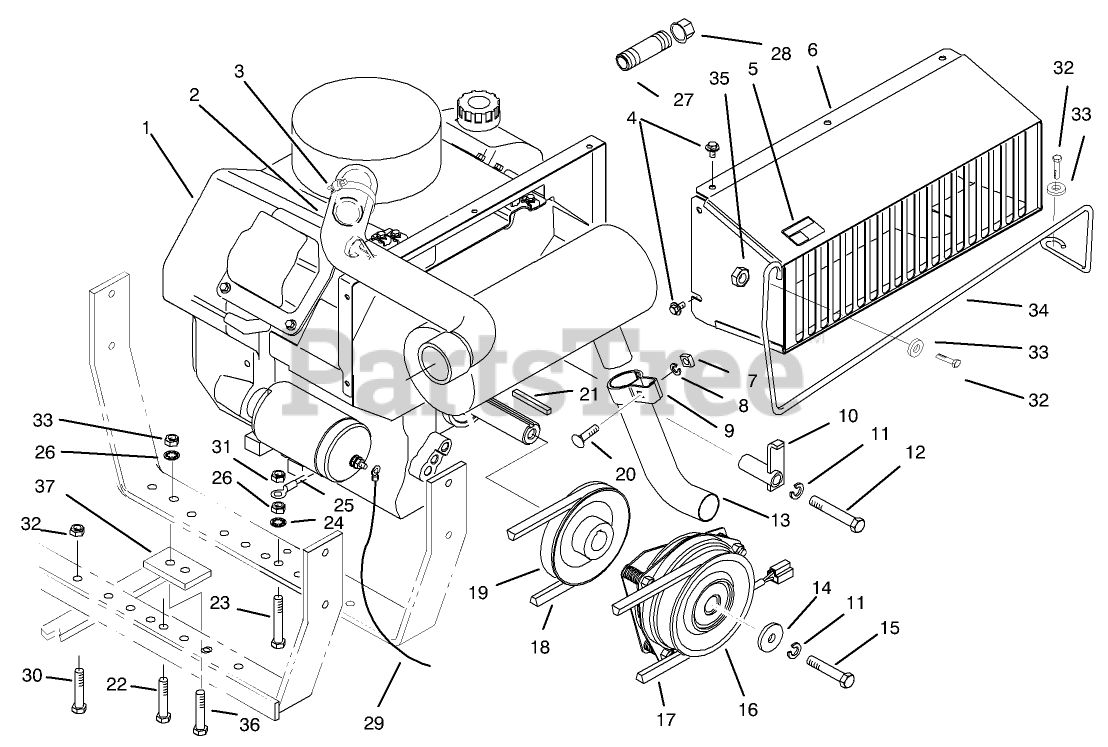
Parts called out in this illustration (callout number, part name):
2	CARB INTAKE HOSE
3	CLAMP-HOSE
4	SCREW
5	DECAL-SURFACE, HOT
6	Duct-Engine
7	NUT-HEX
8	WASHER-LOCK
9	Assembly-Clamp (Incl. Ref. #7, 8 & 20)
10	Anchor Bracket
11	WASHER-LOCK
12	SCREW-HH
13	EXHAUST PIPE
14	WASHER-CLUTCH
15	SCREW-HH
16	BRAKE CLUTCH ASM
17	V-BELT, JACKSHAFT
18	V-BELT, TRACTION
19	ENGINE PULLEY
20	SCREW-CARR
22	SCREW-HH
23	SCREW-HH
24	WASHER-LOCK, INTERNAL
25	WIRE ASM (NEGATIVE)
26	NUT-LOCK, NI
27	NIPPLE-PIPE
28	CAP-PIPE
29	POSITIVE WIRE ASM
30	SCREW-HH
31	NUT-HHF, WHIZ
32	SCREW-HH
33	WASHER-PLAIN
34	GUARD - MUFFLER
35	NUT-LOCK, NI
36	SCREW-HH
37	Guard-Tank
